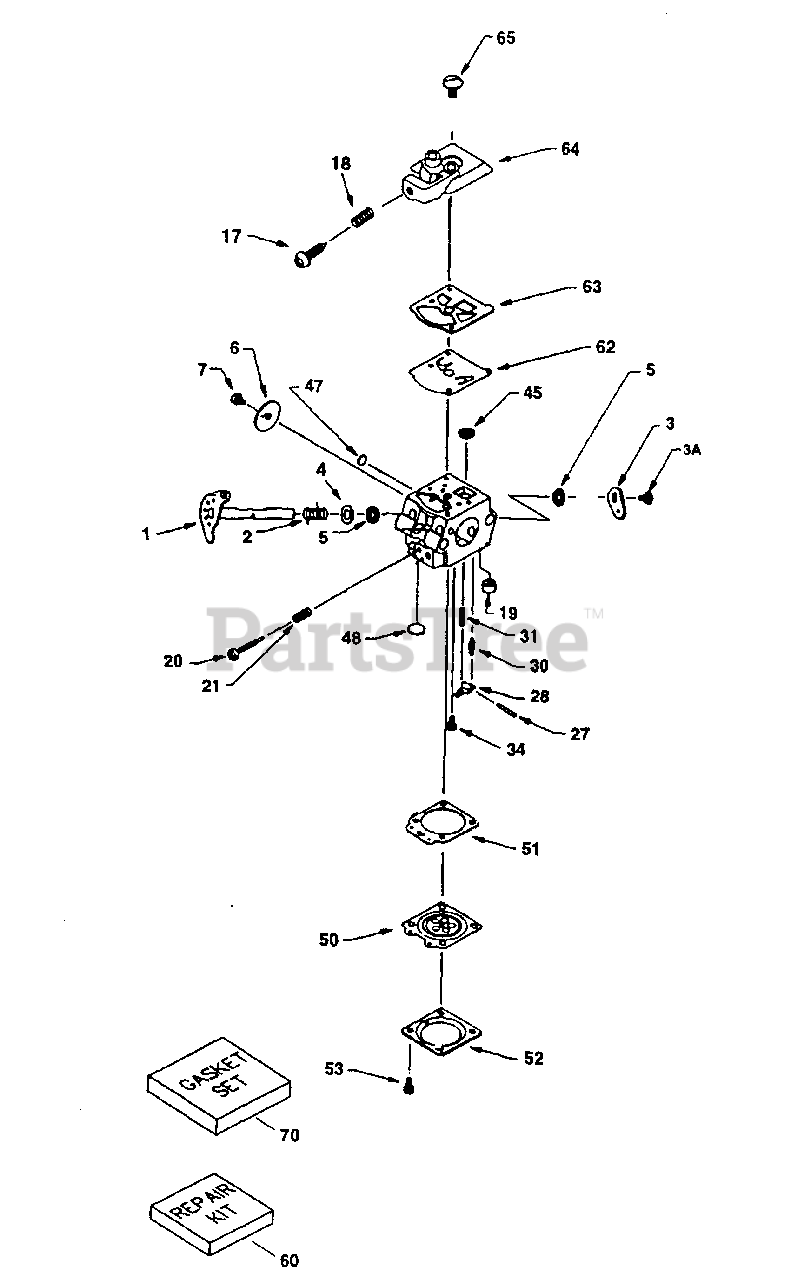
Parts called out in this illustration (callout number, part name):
1	Throttle Shaft & Lever Ass'y.
2	Throttle Return Spring
3	Dust Seal Retainer
3A	Dust Seal Retainer Screw
4	Dust Seal Washer
5	Dust Seal
6	Throttle Shutter
7	* Throttle Shutter Screw
17	Idle Speed Screw
18	Tension Spring
19	Check Valve Nozzle
20	* Idle Mixture Screw
21	Idle Tension Spring
27	* Hinge Pin
28	* Metering Lever
30	* Inlet Needle
31	* Metering Lever Spring
34	* Metering Lever Pin Screw
45	* Fuel Inlet Screen
47	* Welch Plug
48	* Welch Plug
50	* Diaphragm (Included in 60 & 70)
51	* Cover Gasket (Included in 60 & 70)
53	Cover Screw
60	Repair Kit (Incl. items marked PK in notes) Incl. (1) each of part #'s6322 97, 632298, 632300A, 632301,632303, 6 32304, 632315A, 632316,632318, 632376 , 632476, 632721,632726, 650506
62	* Pump Diaphragm (Included in 60 & 70)
63	* Pump Gasket (Included in 60 & 70)
64	Pump Cover
65	Pump Cover Screw
70	Diaghragm/Gasket Set Incl. 50, 51, 62 & 63
